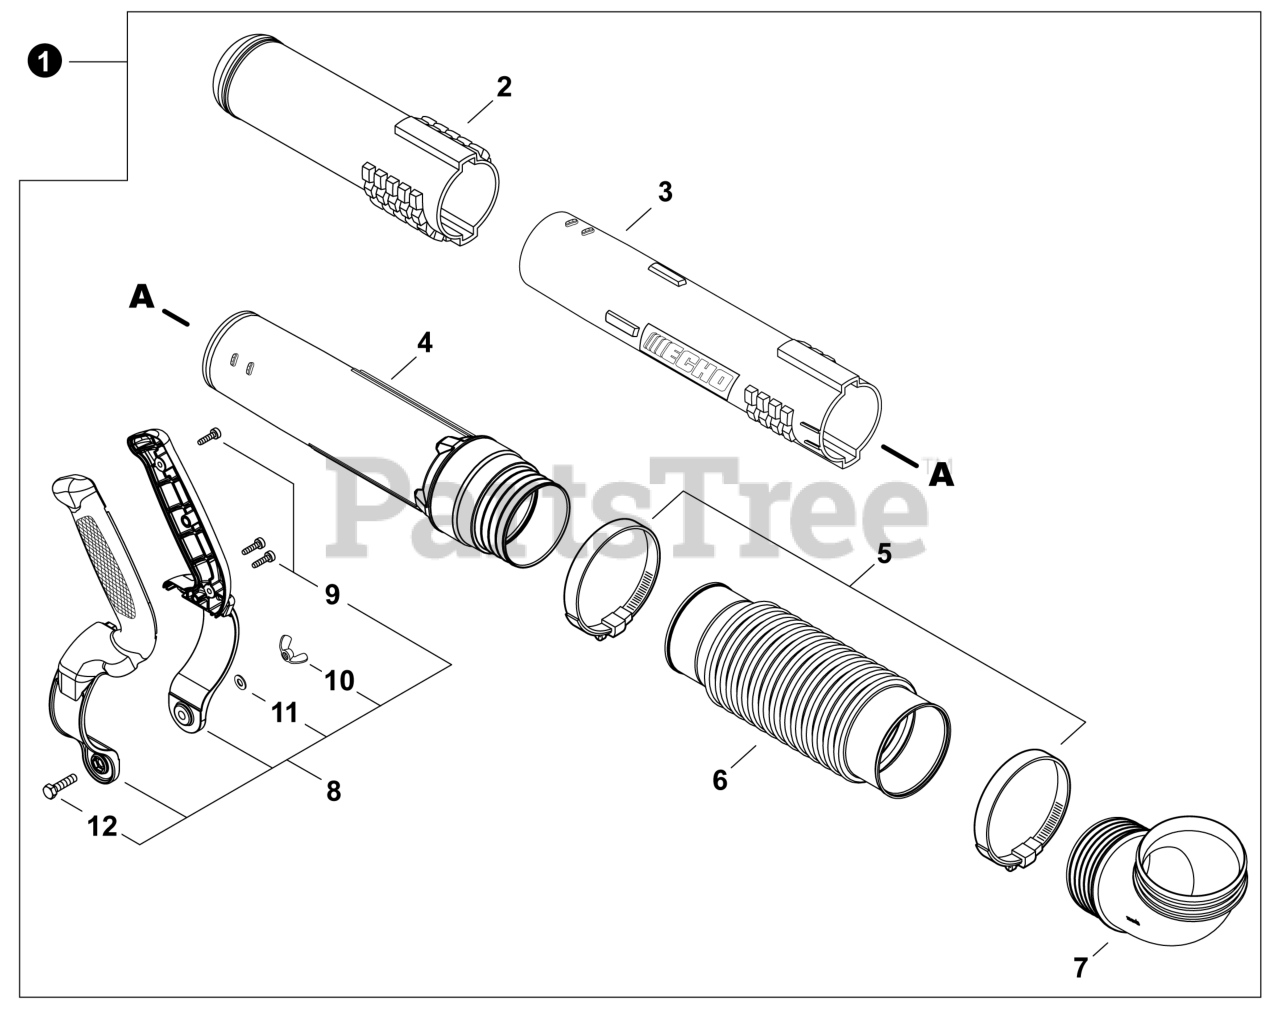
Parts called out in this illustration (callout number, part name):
1	TUBE KIT, BLOWER, HIP MOUNT
2	TUBE, BLOWER - NOZZLE
3	TUBE, BLOWER - STRAIGHT
4	TUBE, BLOWER - SWIVEL
5	CLAMP - BAND 77.8 MM / 101.6 MM
6	TUBE, BLOWER - FLEXIBLE
7	TUBE, BLOWER - ELBOW
8	HANDLE KIT - BLOWER TUBE
9	BOLT, TORX 4x16
10	NUT, WING 6
11	WASHER 6.5x11.5x0.8
12	BOLT 6x25
